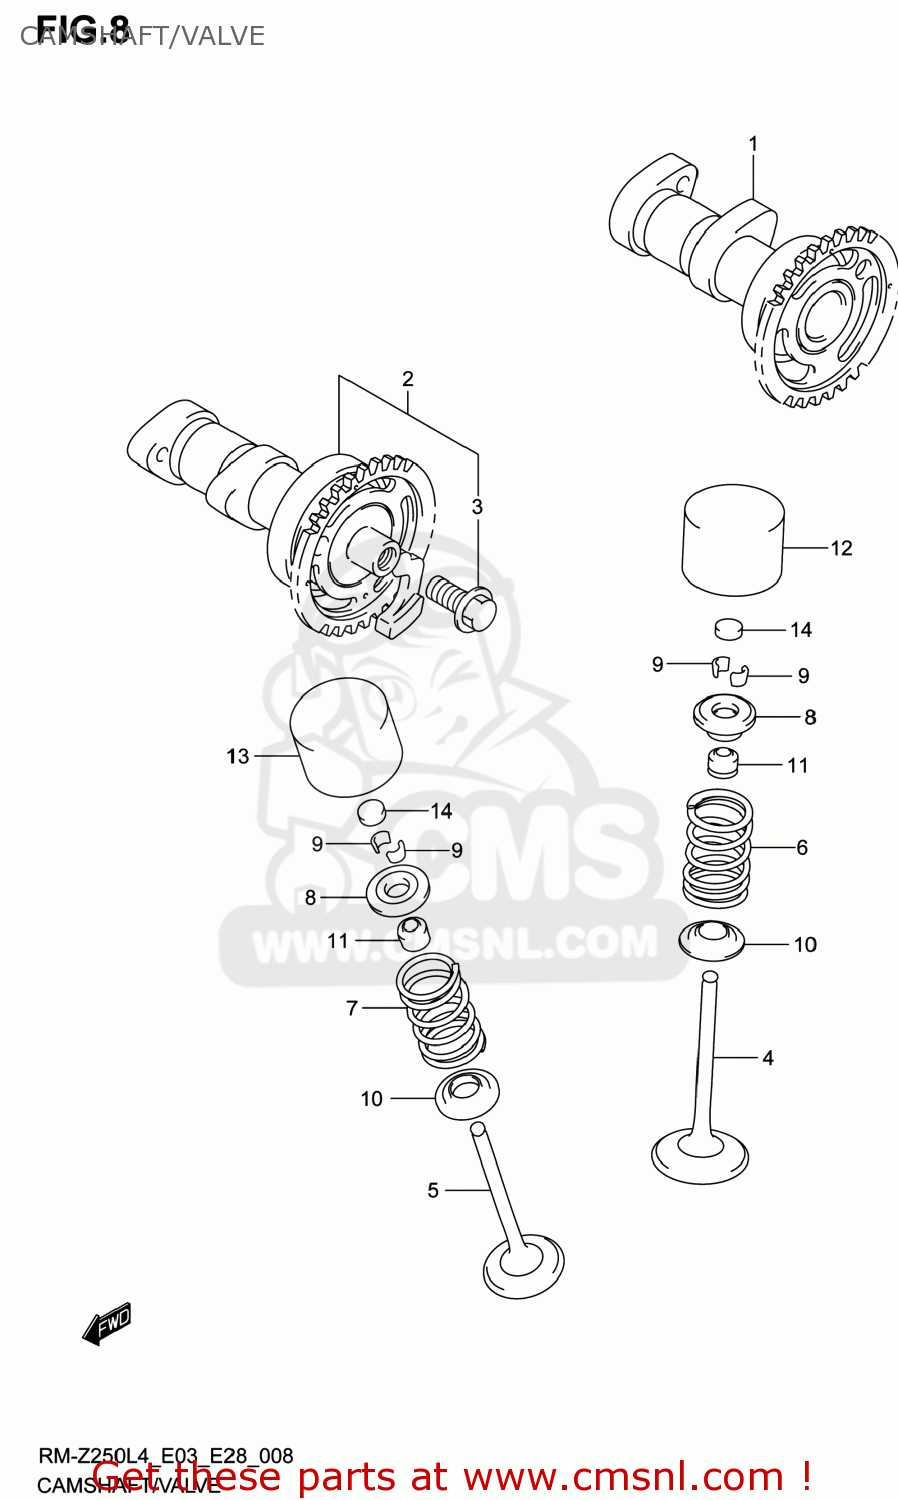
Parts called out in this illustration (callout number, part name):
1	CAMSHAFT,INTAKE
2	CAMSHAFT,EXHAUST
3	BOLT(6X12)
4	VALVE,INTAKE
5	VALVE,EXHAUST
6	SPRING,VALVE
7	SPRING,VALVE
8	RETAINER,VALVE SPRING
9	COTTER VALVE
10	SEAT,VALVE SPRING
11	SEAL,OIL(4.5X10X8)
12	TAPPET
13	TAPPET,EXHAUST
14	SHIM,TAPPET
15	SHIM SET,TAPPET
16	CASE,TAPPET SHIM
